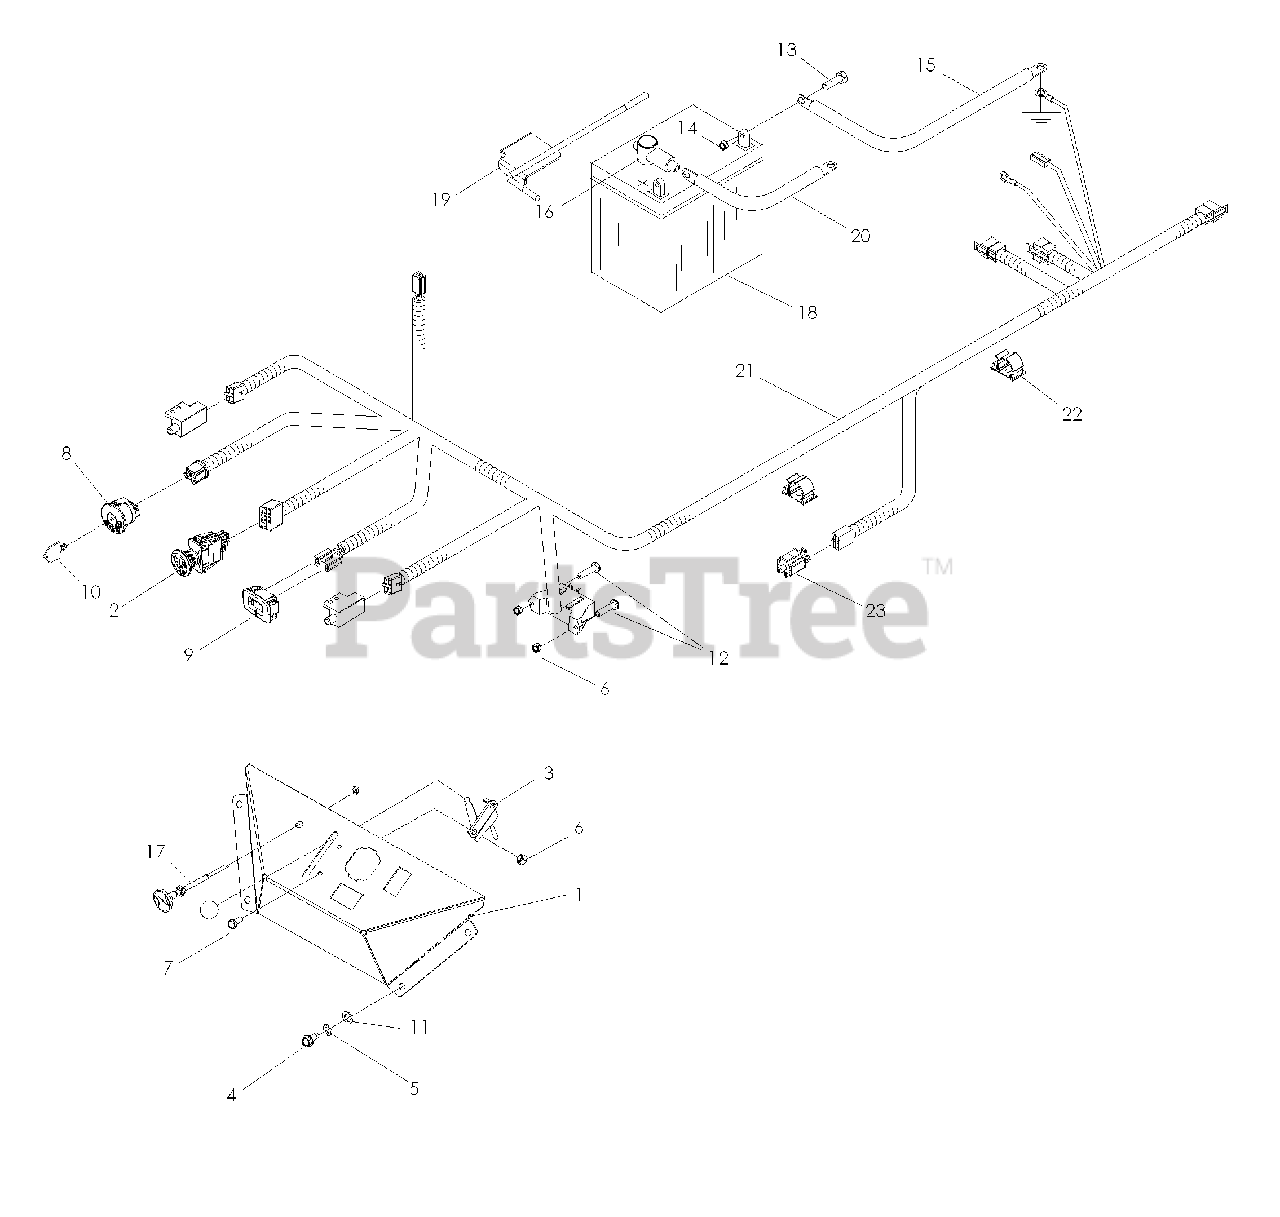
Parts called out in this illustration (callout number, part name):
2	SWITCH, PTO 10 AMP
3	THROTTLE CABLE
4	SCREW 1/4-20 x 5/8
5	WASHER, 1/4 SPLIT LOCK
6	NUT #10-24 HEX NYLOC
7	HCS #10-24 x 1/2
8	IGNITION SWITCH
9	HOUR METER
10	KEY, IGNITION
11	WASHER, 1/4 FLAT
12	SCREW #10-24 x 7/8 SLT HD
13	HCS 5/16-18 x 3/4
14	NUT 5/16-18 HEX NYLOC
15	CABLE, NEGATIVE
16	INSULATOR-BATTERY
17	CHOKE CNTRL / LZ25 ONLY
18	BATTERY, DRY
19	HOLD DOWN, BATTERY
20	CABLE, POSITIVE
22	WIRE CLIP PUSH-MOUNT
23	SWITCH, BRAKE
